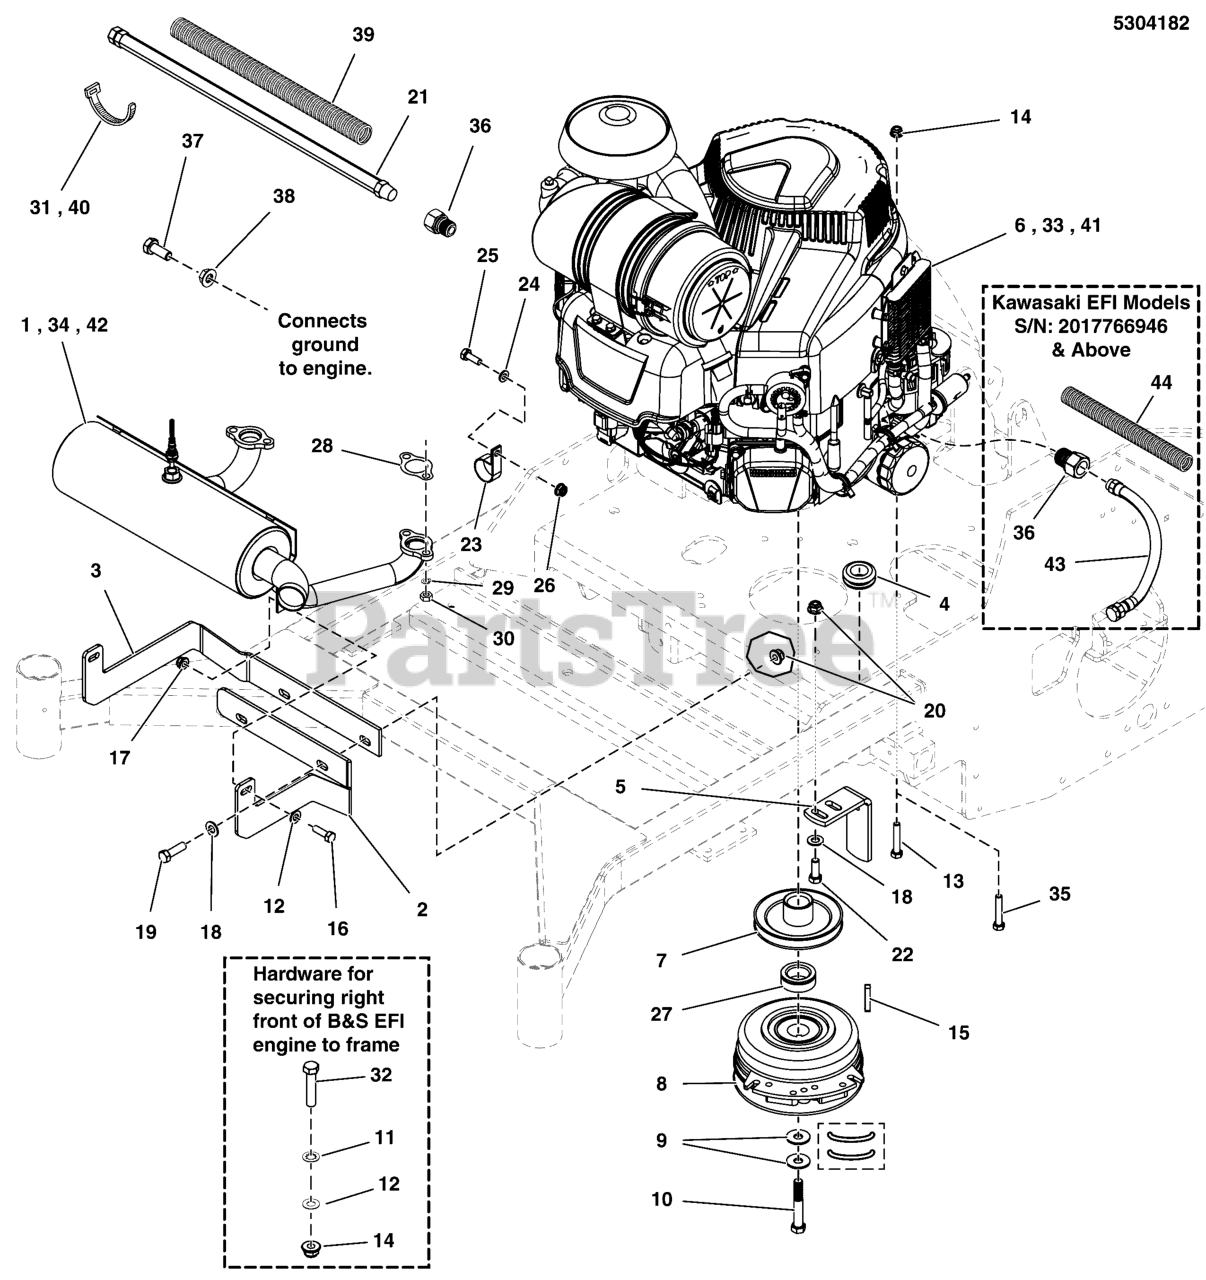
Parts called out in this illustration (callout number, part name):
1	MUFFLER, 26/28, B&S VANG, EFI TWR/WALK
2	PLATE, EXHAUST BRACKET LH - BLK
3	PLATE, EXHAUST BRACKET RH - BLK
4	GROMMET, 7/8"ID, 1/4" THICK STK
5	ANCHOR, CLUTCH - BLK
7	PULLEY, CRANKSHAFT, 1.1255 ID X 4.50 OD
8	CLUTCH WARNER 200 FT-LB 1.13 X 6.323
9	BELLEVILLE WASHER, 1.1875 X .442 X .098
10	BOLT, CRANKSHAFT, 7/16 X 2-3/4, PATCH, CZ
11	WASHER, 5/16" Internal Tooth Lock
12	WASHER, 5/16" SAE
13	BOLT, 5/16-24 X 1-3/4, GD8, PHOS
14	NUT, 5/16-24, TOP LOCK FLANGE, GD8 PHOS
15	KEY, 1/4" SQ. X 1-1/4
16	BOLT, 5/16-18 X 1" GRD5 YZ
17	NUT, 5/16-1/8, HEX, CNTR LK, ZINC PHOS/OIL
18	WASHER, 3/8 SAE
19	BOLT, 3/8-16 X 1-1/4" GD5 CZ
20	NUT, 3/8 - 16 HEX NYLOCK FLANGE
21	HOSE, OIL DRAIN
22	BOLT, 3/8-16 X 1" GD5 CZ
23	CLAMP, VINYL INSULATED, 1.00
24	WASHER, 1/4 SAE
25	BOLT, 1/4"-20 X 3/4" GD5 YZ
26	NUT, 1/4-20 Hex Nylock Flange
27	SPACER, 1.13 X 1.75 X .63
28	GASKET, EXHAUST
29	WASHER, Light Lock, 5/16
30	NUT, HEX, M8-1.25, CZ, GD 8.8
31	TIE,SELF-LOCKING, 24"
32	BOLT, 5/16-24 X 1-1/2, GD8, PHOS
34	MUFFLER, 26, KAWASAKI, 801 BLOCK, SRS Z2
35	BOLT, HEX FLG, SER, GD5 3/8-16 X 1-1/4" PACH CZ
36	ADAPTER, Oil Drain
37	BOLT, M8-1.25 X 20 MM GD 8.8
38	NUT, M8-1.25 Hex Serrated Flange
39	WIRE LOOM, 3/4 ID X 12 IN
40	TIE, SELF-LOCKING, 6"
42	MUFFLER, HORIZONTAL, KAWASAKI
43	HOSE-OIL DRAIN .375ID 16.5L
44	WIRE LOOM, 3/4 ID X 9 IN
